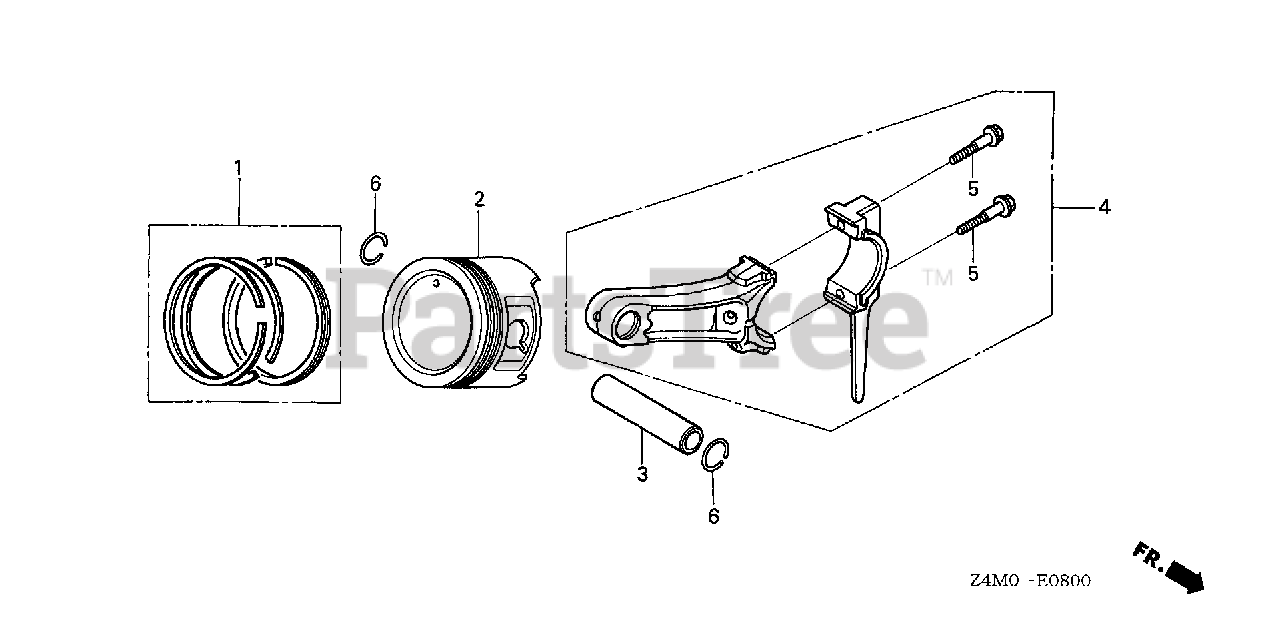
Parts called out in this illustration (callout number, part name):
1	RING SET, PISTON (STD) (RIKEN)
1	RING SET, PISTON (0.25) (TPR)
1	RING SET, PISTON (0.25) (RIKEN)
1	RING SET, PISTON (0.50) (TPR)
1	RING SET, PISTON (0.50) (RIKEN)
2	PISTON (STD)
2	PISTON (0.25)
2	PISTON (0.50)
3	PIN, PISTON
4	ROD ASSY., CONNECTING
5	BOLT, CONNECTING ROD (6X34.5)
6	CLIP, PISTON PIN (18MM)
